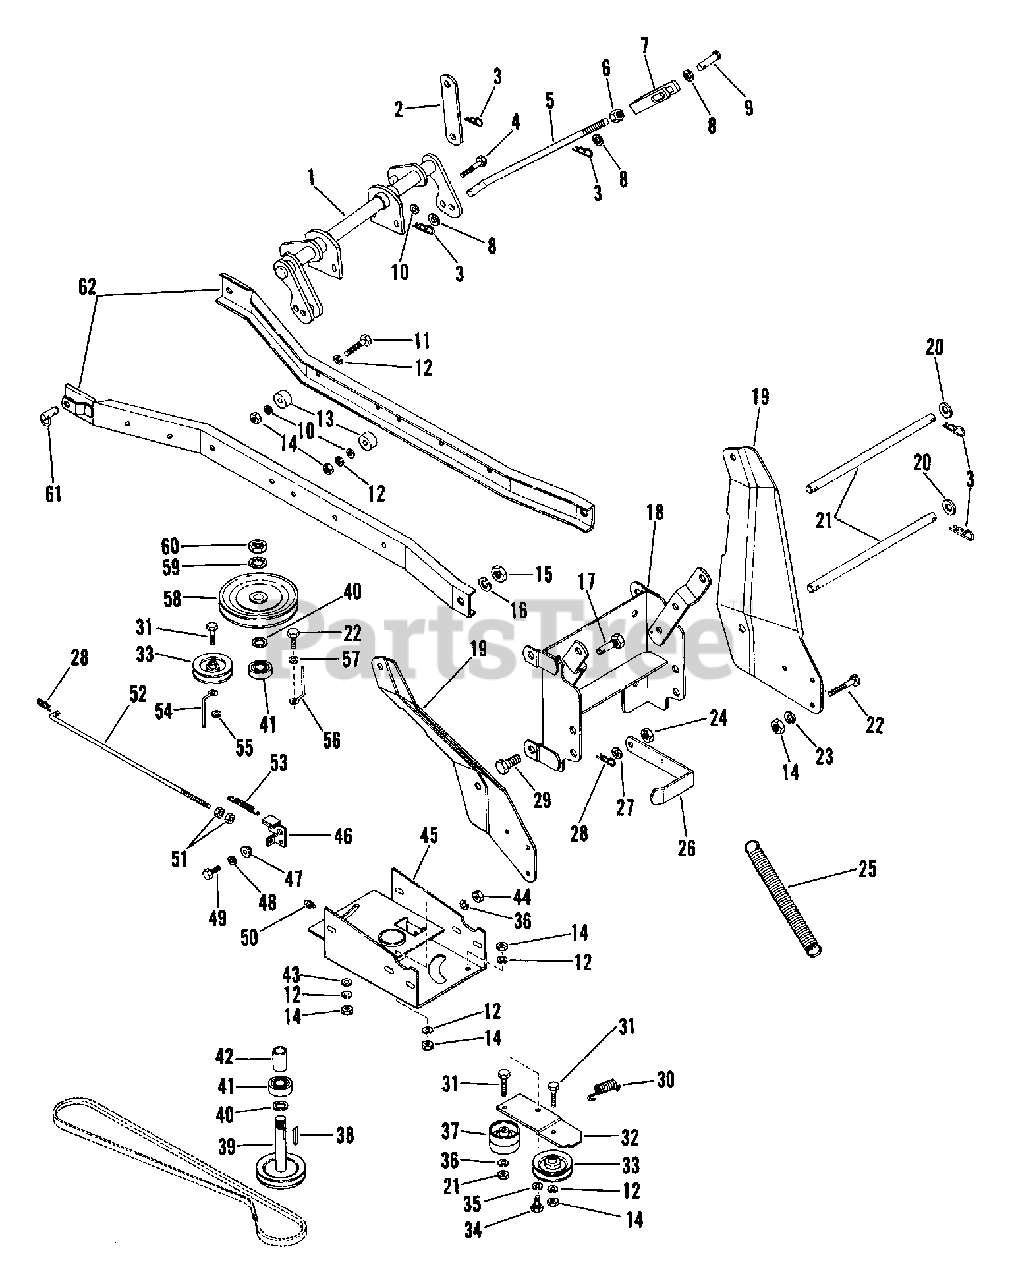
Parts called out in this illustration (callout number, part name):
1	LIFT BELLCRANK WELDMENT
2	CONNECTING LINK
3	PIN-HAIR INT .09X.188 PL
4	BLT-HEX .38-16X2.00 PL GR5
5	LIFT ROD
6	NUT-JAM .50-13 PL
7	LIFT CLEVIS WELDMENT
8	WSHR-FL-STL .531X1.062X.095 PL
9	PIN-CLEV .494X1.94 YWZC
10	WSHR-FL-STL .38X.875X.083 PL
11	BLT-HEX .38-16X1.75 PL GR5
12	WSHR-LK .375X.115 HVY PL
13	SPACER .406X1.250X.688
14	NUT-HEX .375-16
15	NUT-HEX .625-11
16	WSHR-LK .625X.156 MED PL
17	STUD-WEIGHT
18	MOUNTING BRACKET WELDMENT
19	LIFT ARM RH
19	LIFT ARM LH
20	WSHR-FL-STL.656X1.312X.095 PL
21	PIVOT ROD
22	BLT-HEX .38-16X1.00 PL GR5
23	WSHR-LK .375X.094 MED PL
24	NUT-LK-CTR .50-13
25	SG-TENS .187X1.50X9.94 WLD 40
26	CONTROL HANDLE
27	WSHR-FL-STL .458X.750X.06 PL
28	PIN-HAIR INT .08X.18X1.18
29	BLT-HEX .62-11X1.50 PL GR2
30	SG-TENS .080X.73X3.06 WLD 20
31	BLT-HEX .38-16X1.75 PL GR2
32	IDLER ARM
33	IDLER-V 3.06 X .38
34	SHOULDER BOLT .50 X .281
35	WSHR-FL-STL .511X1.441X.125 PL
36	WSHR-LK .312X.097 PL HVY
37	IDLER-FLAT 2.25 X .38
38	KEY-SQ .188X1.0X.188 SAE 8630
39	DRIVE SPINDLE
40	WSHR-FL-STL .755X1.250X.125
41	BRG-BALL .750X1.781X.61
42	BEARING SPACER .77X1.00X1.655
43	WSHR-FL-STL .406X1.125X.125 PL
44	NUT-HEX .312-18
45	SPINDLE SUPPORT
46	BRAKE ACTUATOR
47	BSHG, FLG .325X.499X.26X.88
48	WSHR-FL-STL.312X.734X.065PL
49	BLT-HEX .31-18X1.00 PL GR5
50	SPIN DRIVE ZERK FITTING
51	NUT-JAM .312-18 PL
52	BRAKE ROD
53	SG-TENS .047X.44X3.37 WLD 1.47
54	BELT FINGER
55	WSHR-FL-STL .382X.812X.023 PL
56	BELT GUIDE
57	WSHR-FL-STL .390X.750X.125 PL
58	PLY-V 6.00 X .75 W/KEY
59	WSHR-LK-INT .750X.050 MED
60	NUT-JAM .75-10 PL
61	HITCH PIN
62	CHANNEL WELDMENT
